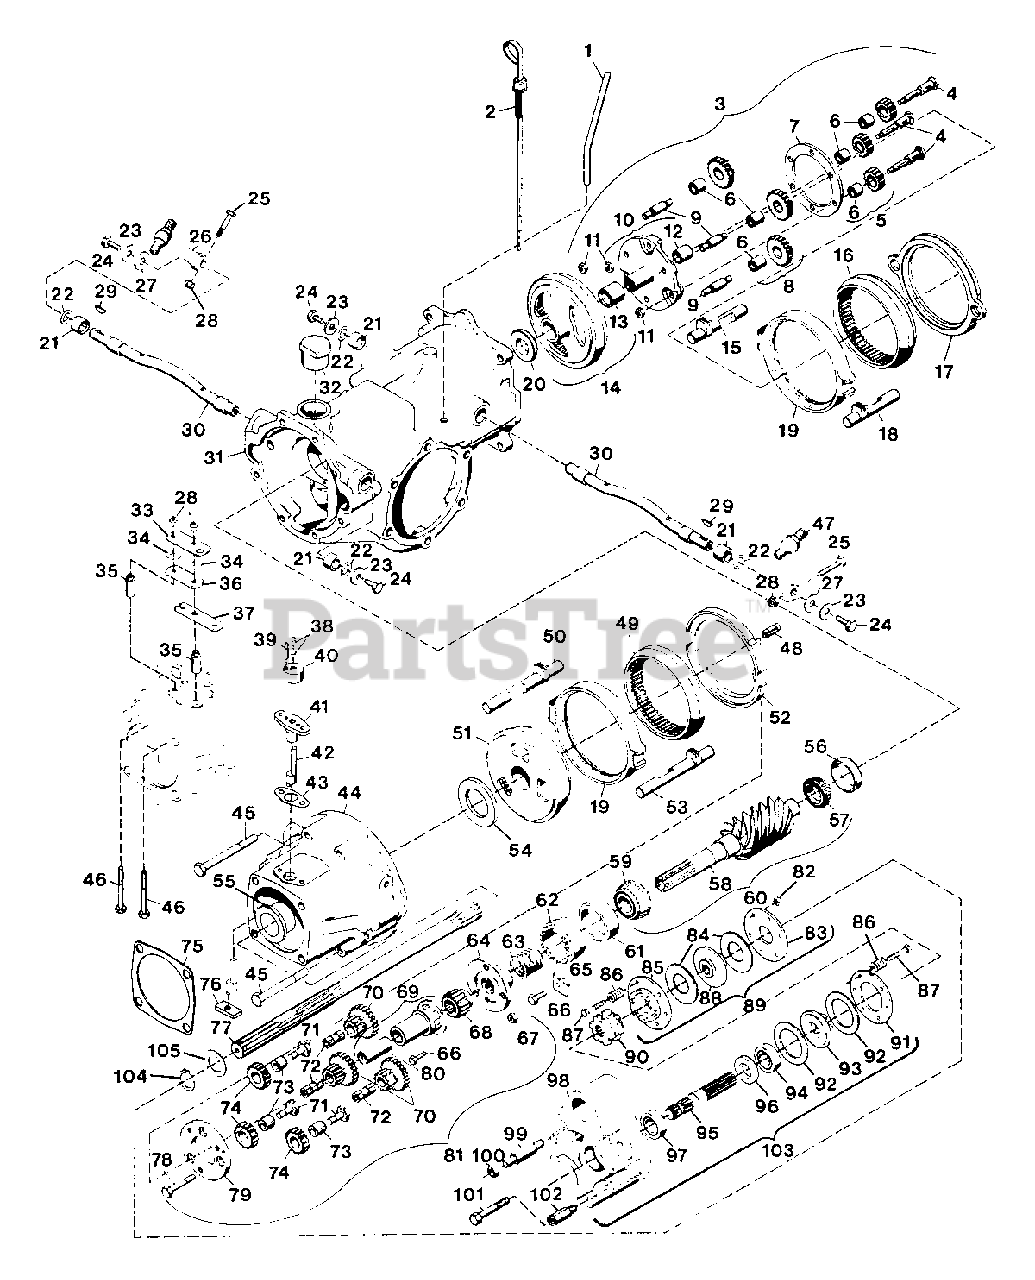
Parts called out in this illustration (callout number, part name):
1	Guide, Dipstick
2	Assembly, Dipstick
3	Assembly, Hi-Lo Planetary
4	Bolt, Orbit Gear
5	Assembly, External Orbit Gear
6	Bushing, .501x.627x.465
7	Spacer, Pin
8	Assembly, Internal Orbit Gear
9	Pin, Hi-Lo Orbit Gear
10	Asm, Planet Gear Carrier
11	Nut, Lock 5/16-18 L.H. Thd.
12	Bushing, .737x.877x.682
13	Bushing, 1.231 x1.502x1.312
14	Asm., Ring Gear and Bushing
15	Rod, Rear Clutch Slide L.H.
16	Gear, Rear Ring
17	Spacer, Rear
18	Rod, Rear Clutch Slide R.H.
19	Assembly, Clutch Cup
20	Plate, Rear Thrust
21	Bushing, .750x1.002x.625
22	O-Ring, .750x1.00
23	Washer, Flat .265x1.250x.063
24	Bolt, Hex 1/4-20x.50
25	Bolt, Hex 5/16-18x2.00
26	Assembly, Fwd-Rev Lever
27	Washer, Flat .812x1.496x.134
28	Nut, Lock 5/16-18
29	Key, Woodruff .125x.625 Hrd #5
30	Shaft, Actuating
31	Chassis
32	Plug, Oil Filler
33	Bracket, PTO Switch
34	Washer, Flat .344x.688x.065
35	Spacer, Shipper Shaft Guide
36	Spacer, Strap
37	Arm, Shifter
38	Screw, Set 3/8-16x.25 HSCKT
39	Pin, Spring .25x.75
40	Body, Shipper Shaft
41	Guide, Shipper Shaft
42	Shaft, Shipper
43	Gasket, Shipper Shaft
44	Assembly, Advance Casting
45	Bolt, Hex 5/16-18x3.25 Gr. 8
46	Bolt, Hex 5/16-18x2.50
47	Assembly, Hi-Lo Lever
48	Pin, Roll
49	Gear, Internal Spur
50	Rod, Clutch Slide L.H.
51	Cone, Reverse Gear
52	Cup, Gear
53	Rod, Clutch Slide R.H.
54	Disc, Friction
55	Bearing, Flange
56	Cup, Roller Bearing
57	Cone, Roller Bearing
58	Weldment, 6-Lead Worm
58	Weldment, 8-Lead Worm
59	Cone, Roller Bearing
60	Welded Worm Shaft Assembly
61	Cup, Roller Bearing
62	Nut, Bearing Adjustment
63	Spacer, Spring Pin Plate
64	Plate, Front Pin
65	Nut, Adjusting
66	Bolt, Hex 1/4-20x.625
67	Nut, Hex 1/4-20
68	Gear, Sun Pinion
69	Assembly, Quill and Bushing
70	Gear, Orbit Spur
71	Bolt, Reverse Idler
72	Pin, Fwd-Rev Orbit Gear
73	Bushing, Reverse Idler
74	Gear, Reverse Idler Spur
75	Gasket, Attachment
76	Block, Trunnion
77	Shaft, Pinion
78	Bolt, Spacer
79	Spacer, Front Pin
80	Bushing,.875x1.000x2
81	Assembly, Fwd-Rev Planetary
82	Nut, Jam 5/16-24
83	Plate, Back
84	Washer, Friction
85	Plate, Dog
86	Spring, Comp. .75x2200 Rate
87	Bolt, Hex 5/16-24x1.75
88	Plate, Drive
89	Assembly, Clutch
90	Dog
91	Plate, Back
92	Disc, Brake
93	Brake, Dog Plate
94	Bearing, Ball .984x2.047x.591
95	Shaft, Quick Hitch
96	Seal, Oil
97	Bearing, Ball .984x2.047x.590
98	Casting, Quick Hitch
99	Stud, Quick Hitch
100	Nut, Hex 1/2-13
101	Bolt, Hex 1/2.13x1.00
102	Stud, Quick Hitch
103	Attachment Adapter
104	Ring, Retaining
105	Race, Bearing Thrust
